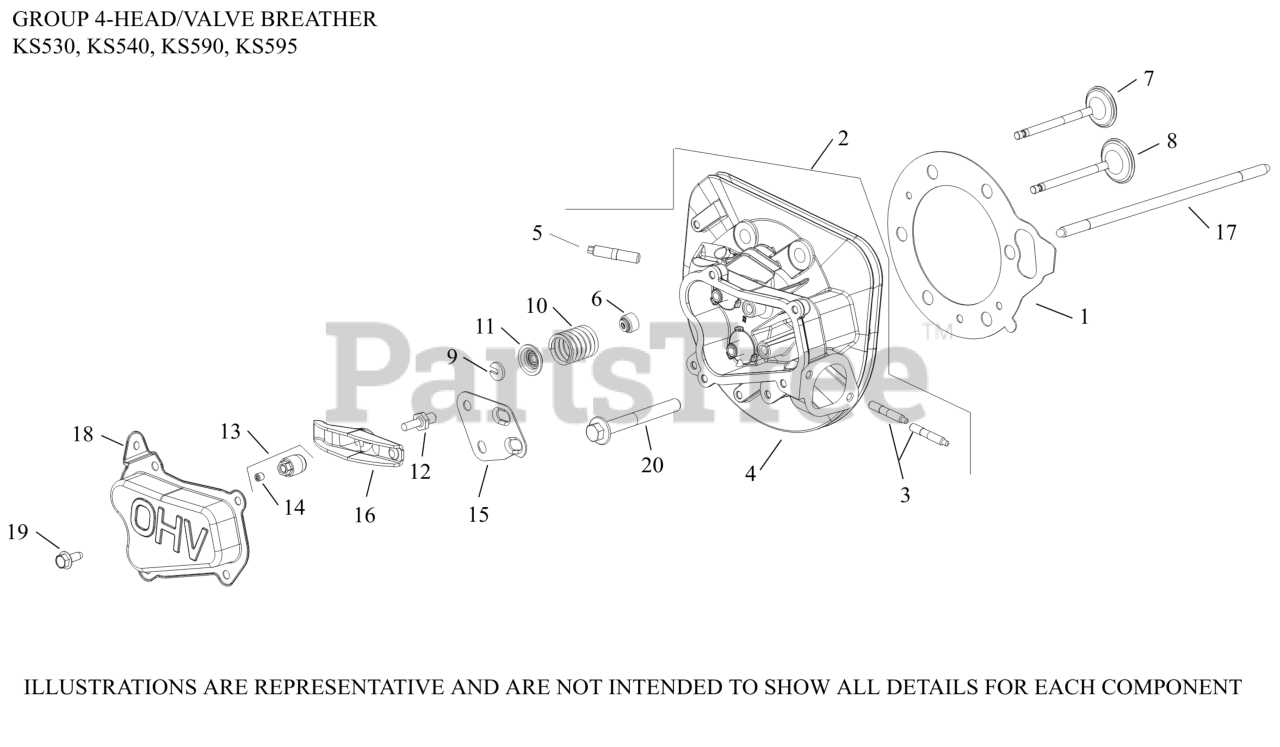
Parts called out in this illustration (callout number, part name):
1	GASKET, CYLINDER HEAD
2	HEAD ASSY (STUD INSTALLATION)
3	STUD, INTAKE MANIFOLD
4	HEAD, CLYLINDER-USE 22 318 03-S
5	STUD, EXHAUST-USE 25 072 36-S
6	SEAL, VALVE STEM
7	VALVE, EXHAUST
8	VALVE, INTAKE
9	LOCK, RETAINER
10	SPRING, VALVE
11	CAP, VALVE SPRING
12	STUD, ROCKER
13	PIVOT, ROCKER ARM-USE 20 599 04-S
13	ROCKER PIVOT ASSY
14	SCREW, SET
15	PLATE, PUSHROD GUIDE
16	ARM, ROCKER
17	ROD, PUSH
18	COVER, VALVE
19	SCREW, THREAD FORMING
20	SCREW, HEX FLANGE
